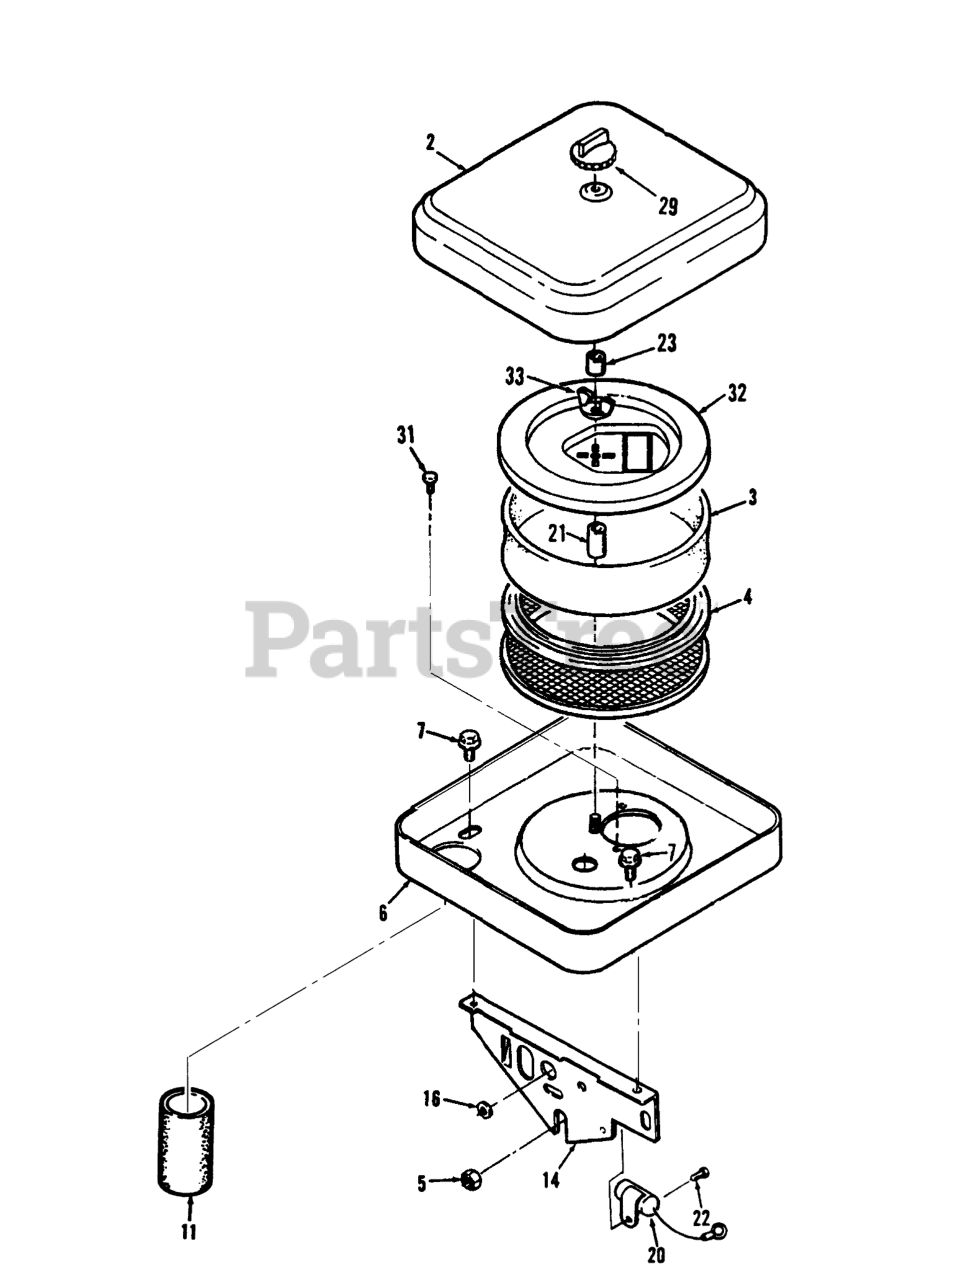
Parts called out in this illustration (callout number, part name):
2	CHROME-AIR CLEANER
3	AIR CLEANER ELEMENT
4	Element-Air Cleaner
5	Washer
6	AIR-CLEANER HOUSING
7	SCREW-TAPPING
11	AIR INTAKE TUBE
14	SUPPORT-AIR CLEANER
16	Grommet
20	Condenser
21	SPACER-1" LG
22	SCREW #10-32 X 5/8
23	SPACER-RUBBER
31	MACHINE SCREW
32	Cover-Element
33	1/4-20 WING NUT
